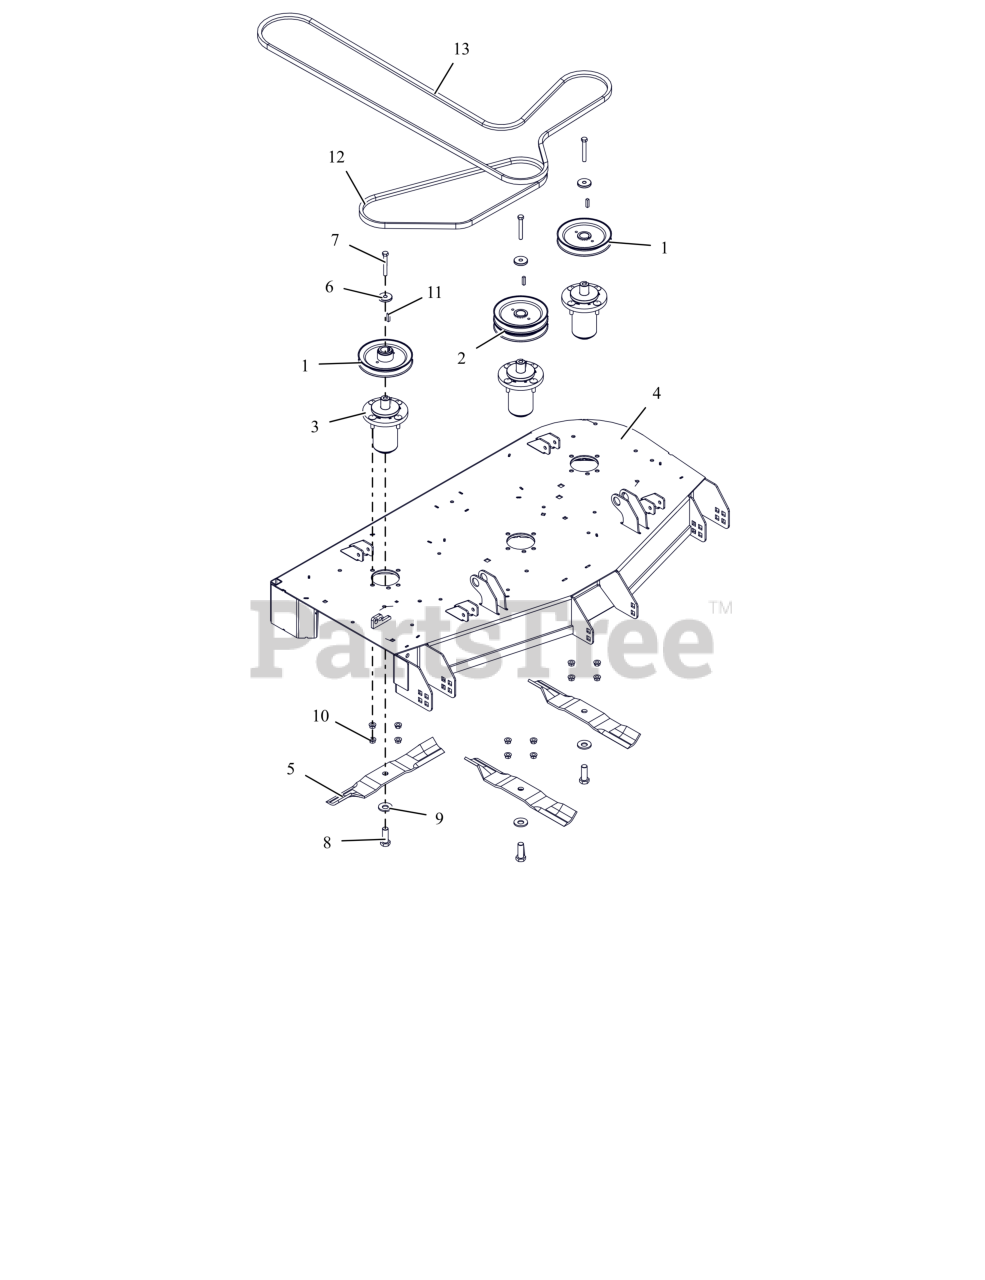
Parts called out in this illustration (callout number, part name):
1	PULLEY, SINGLE -1.000 ID X 6.000 OD
2	PULLEY- DOUBLE
3	ASM, MAINT FREE ALUM SPINDLE
4	KIT,DECK-48" W/DECALS -ARIENS
5	BLADE, 16.19" MOWER (HI-LIFT)
6	RETAINER, SHEAVE
7	BLT, HEX .38-16X2.75 G8 ZCC
8	BLT, HEX .62-18X1.75 G8 ZCC
9	WSHR-BLVL .669X1.535X.138
10	NUT-LK-CTR-FLG .375-16 GF ZCC
11	KEY, SQ .25X.25X1.00 RC 40-50
12	V-BELT, B-COGGED
13	V-BELT, HB SECTION
